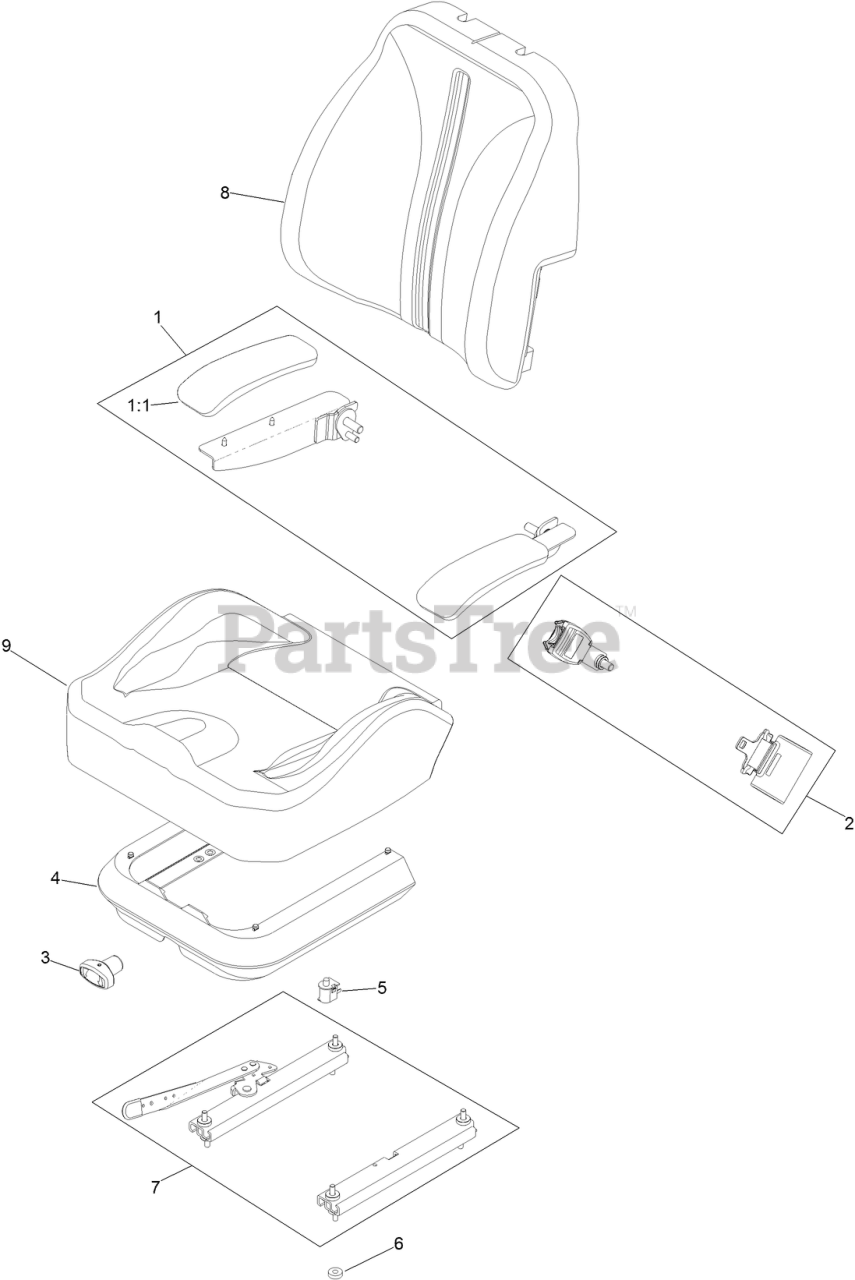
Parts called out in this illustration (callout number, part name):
1	ARMREST KIT
1:1	CUSHION-REST, ARM
2	SEAT BELT KIT
3	KNOB-ADJUSTER
4	COVER-SKIRT W/FASTENERS
5	SWITCH-BAIL
7	TRACK ASM
8	COVER-BACK, SEAT
9	COVER-BOTTOM, SEAT
